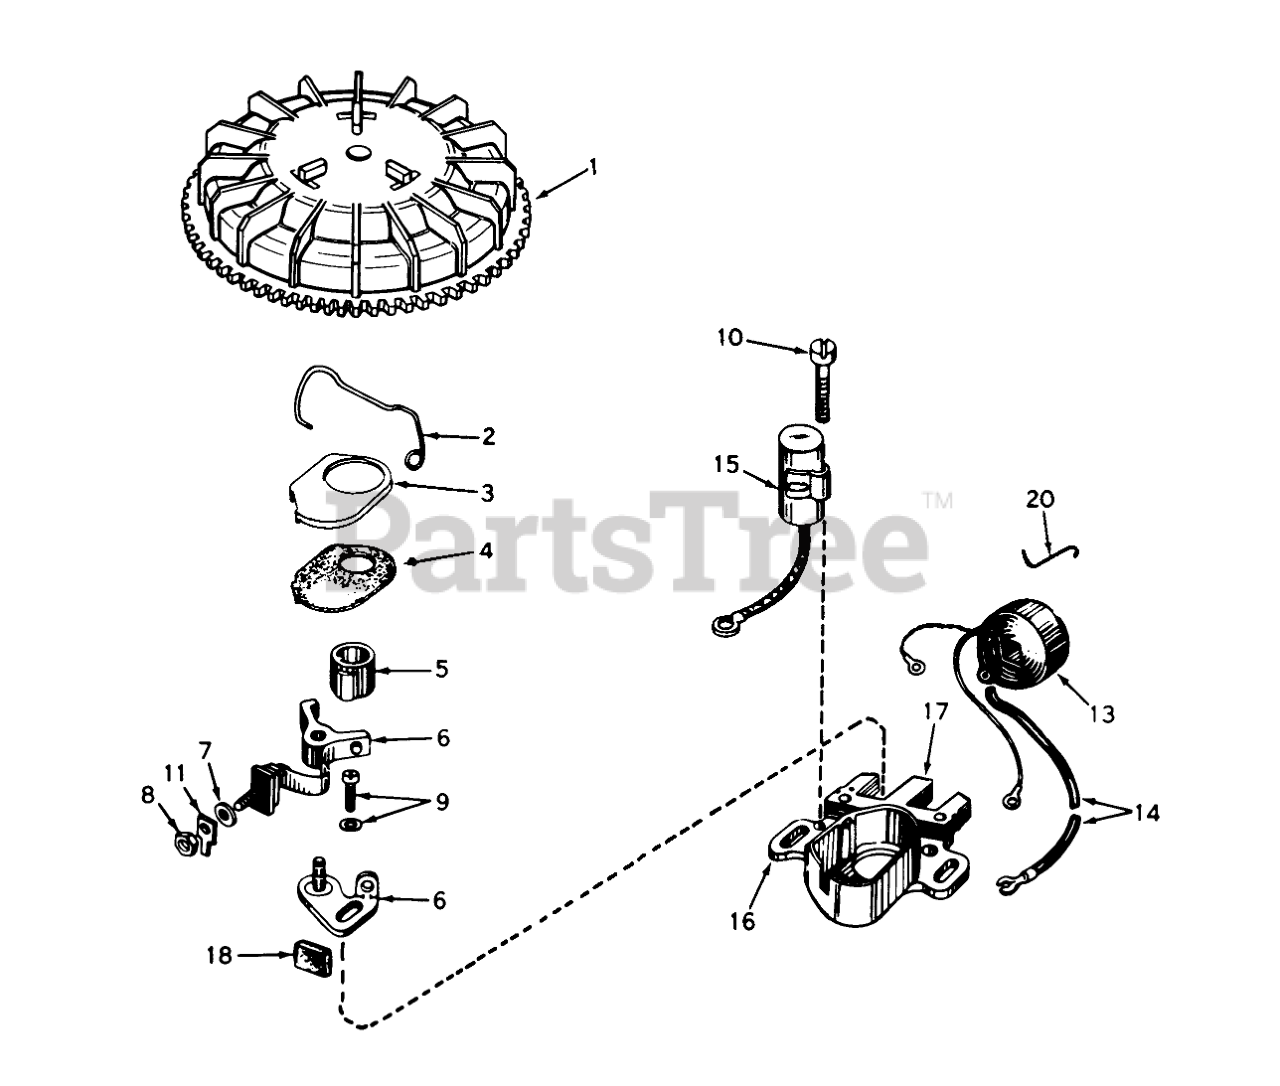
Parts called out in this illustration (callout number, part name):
1	Flywheel (Incl. Ref. #3 & 4)
2	Spring Breaker Box
3	Cover-Dust
4	Gasket, Dust Cover
5	Cam, Breaker
6	Breaker Assy.
7	Washer
8	DECAL
9	Breaker Screw
10	Condenser Screw
11	Terminal, Ground
13	Coil Assembly (Incl. Ref. #14)
14	Wire, Lead
15	Condenser
16	Core & Plate
17	Stator Assembly (Incl. Ref. #2, 3, 4, 6 thru 16, 18 & 20)
18	Felt,Cam Wiper
20	Clip, Coil
